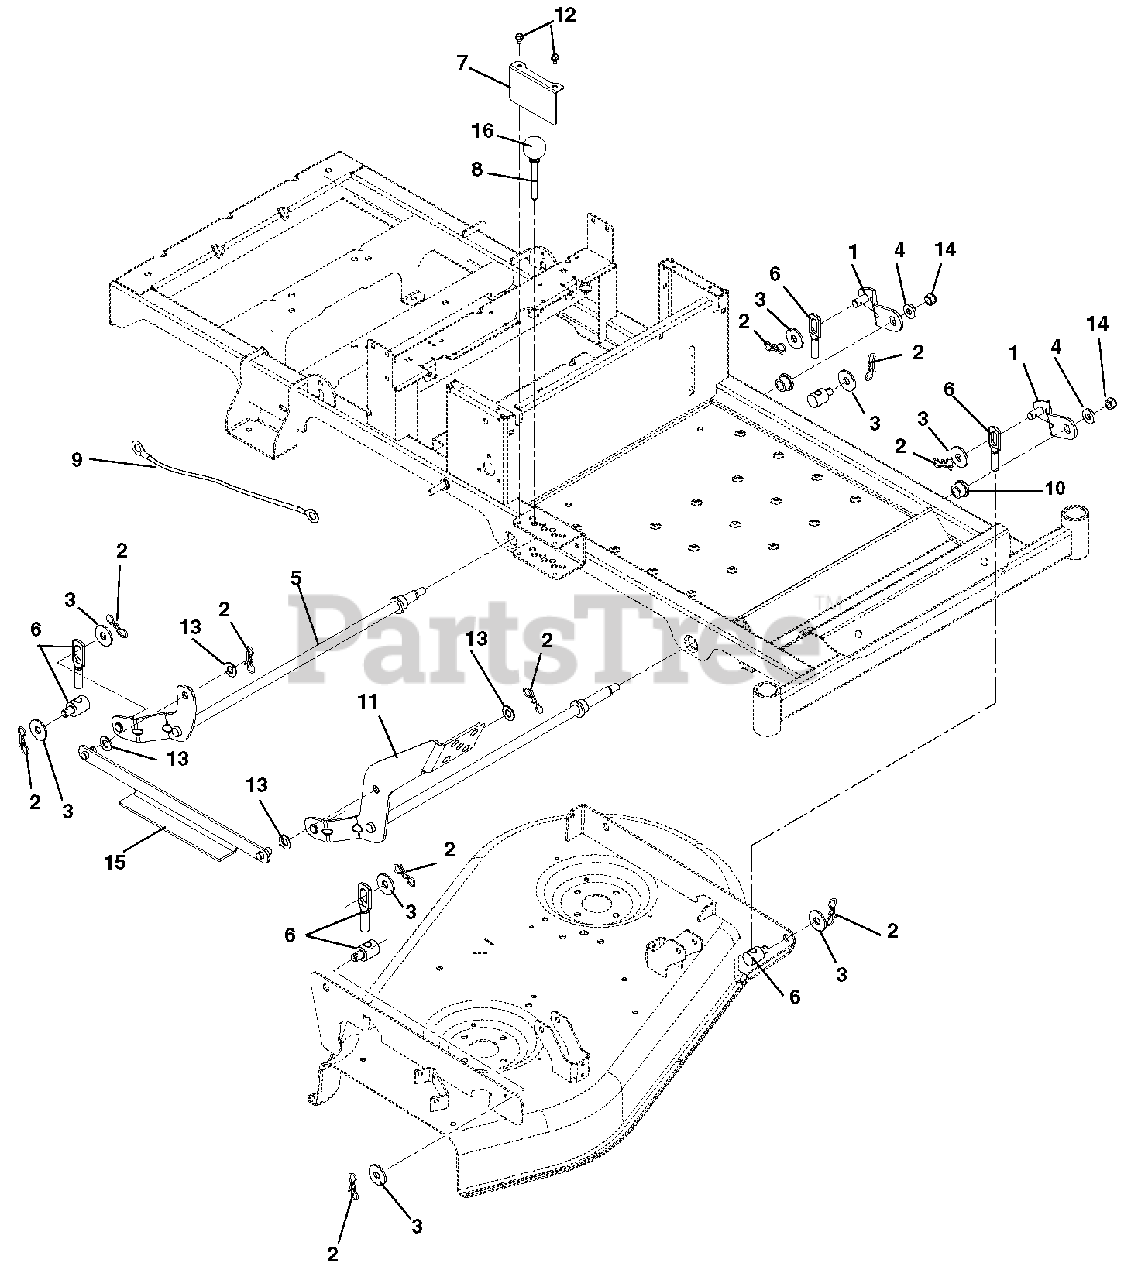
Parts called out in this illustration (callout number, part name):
1	Weldment, Lift Arm
2	Pin, Bow Tie Locking Cotter .091 x 1.875
3	Washer, Flat-STL.511 x 1.441 x .125
4	Washer, Flat-Steel .43 x 1.00 x .0160
5	Weldment, Rear Deck Lift Shaft
6	Assembly, Deck Link
7	Guard, Deck Lift
8	Pin, Deck
9	Lanyard, Galvanized 12"
10	Bushing, Flange .627 x .879 x .469 x 1.120
11	Weldment, Deck Lift Pedal
12	Screw, Tap .25-20 x .37
13	Washer, Flat-Nylon .52 x 1.00 x .08
14	Nut, Nyloc 7/16-20
15	Weldment, Lift Link
16	Knob, Ball - Black 1.47" .375-16
